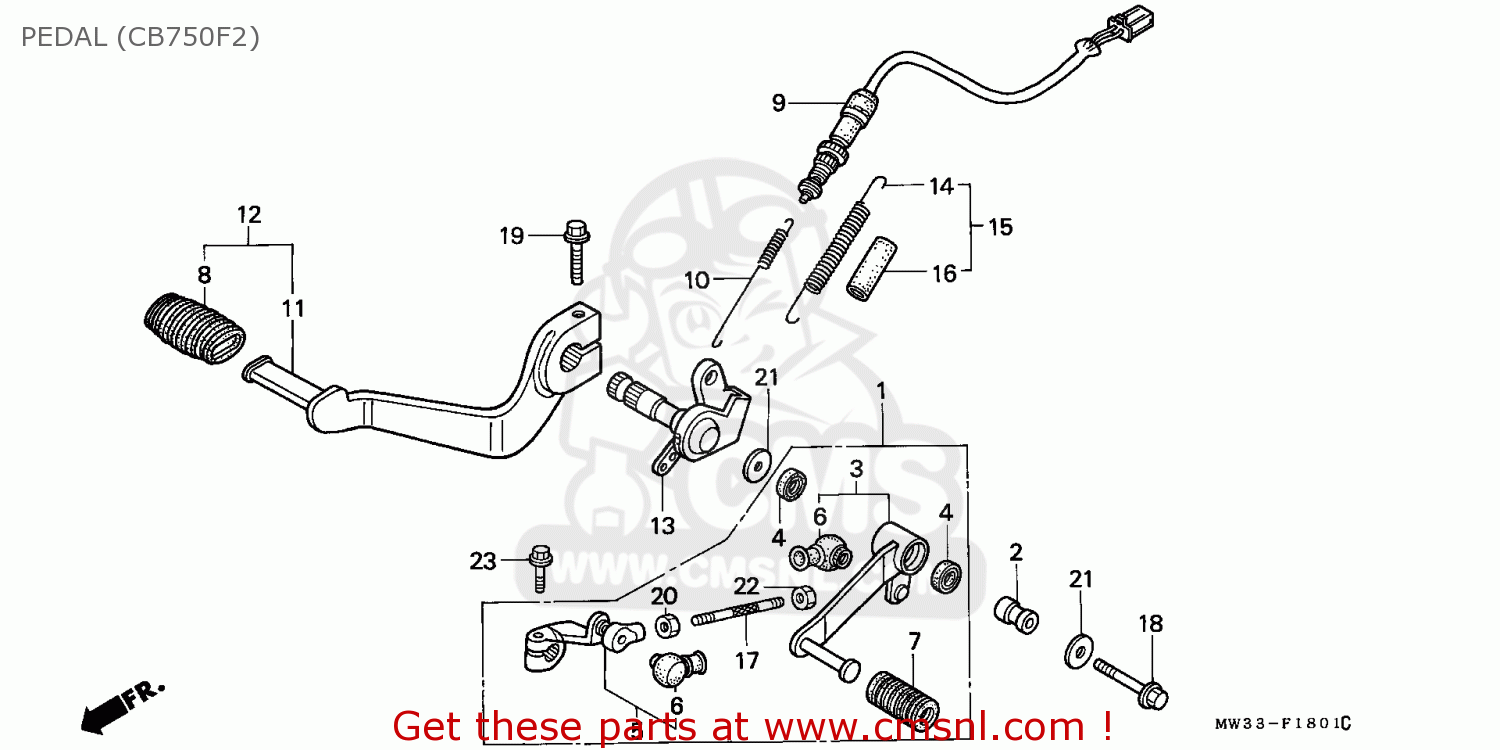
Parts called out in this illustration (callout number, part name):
2	COLLAR,GEAR CHNGE
3	PEDAL COMP.,CHANG
4	RUBBER,DUST SEAL
5	ARM COMP.,CHANGE
6	COVER DUST
7	RUBBER,CHANGE PED
8	RUBBER,CHANGE
9	SWITCH ASSY.,RR.S
10	SPRING,STOP SW
12	PEDAL ASSY,REAR B
13	SPINDLE COMP.,RR.
15	SPRING SET,BRK PE
16	TUBE,BRK PEDAL SP
17	BOLT,TIE-ROD
18	BOLT,FLANGE,8X45
19	BOLT,FLANGE 8X35
20	NUT,GOVERNOR ARM
21	WASHER,8MM
22	NUT.,HEX.,6MM
23	BOLT FLANG 6X20
